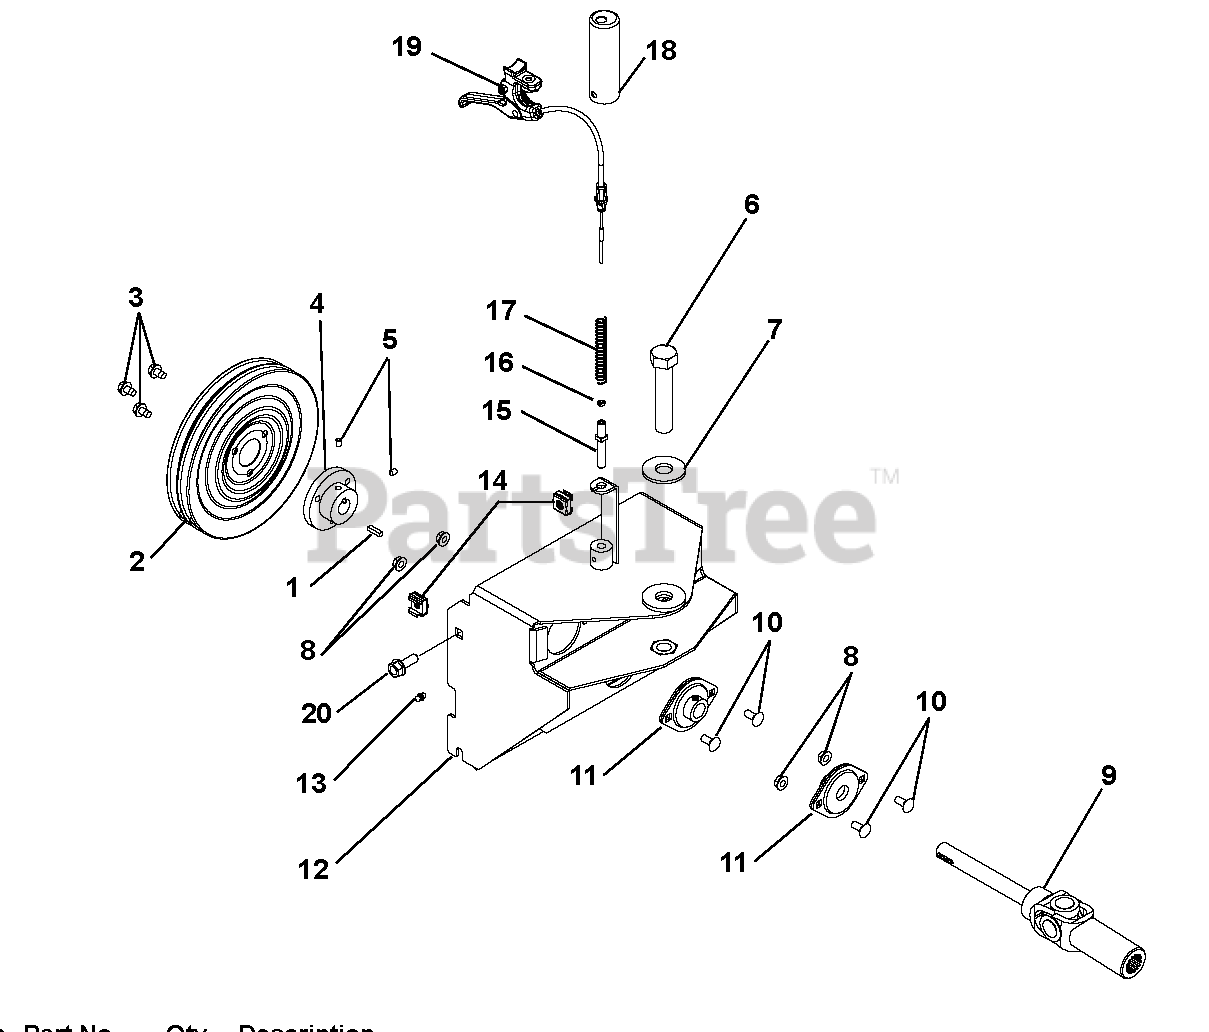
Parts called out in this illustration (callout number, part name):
1	Key, Square .188 x .75 x .188
2	Pulley, Attachment
3	Screw, Tapping Hex Washer Head Thread Rolling .31-18 x .50
4	Hub, Pulley
5	Screw, Set Socket Head Cup Point Nylon Oil Hardened .25-20 x .38
6	Bolt, Hex .75-16 UNF x 3.75
7	Washer, Flat Steel .812 x 2.00 x .148
8	Nut, Locking Top Flange .31-18
9	Driveline
10	Bolt, Round Head Square Neck .31-18 x .75
11	Bearing
12	Mounting Frame
13	Fitting, Lube .25-28 x .256
14	Nut, Retainer .38-16
15	Pin, Swing
16	Nut, Hex 10-24
18	Cap, Vinyl
19	Cable, Remote Brush Lock
20	Bolt, Serrated Hex Washer Head .38-16 x .75
